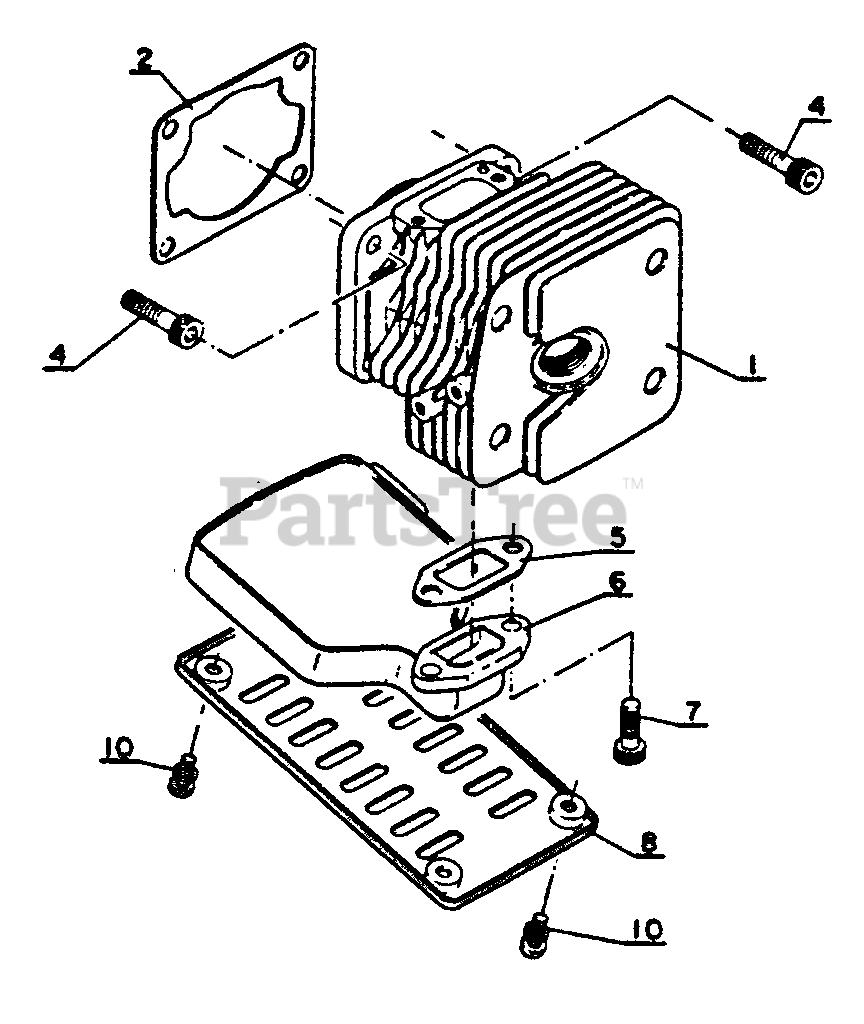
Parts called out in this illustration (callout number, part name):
1	CYLINDER
2	GASKET, CYLINDER
4	BOLT 5×20
5	GASKET, EXHAUST
6	MUFFLER
7	SCREW - 5×15
8	COVER, MUFFLER
10	SCREW - 4×10
